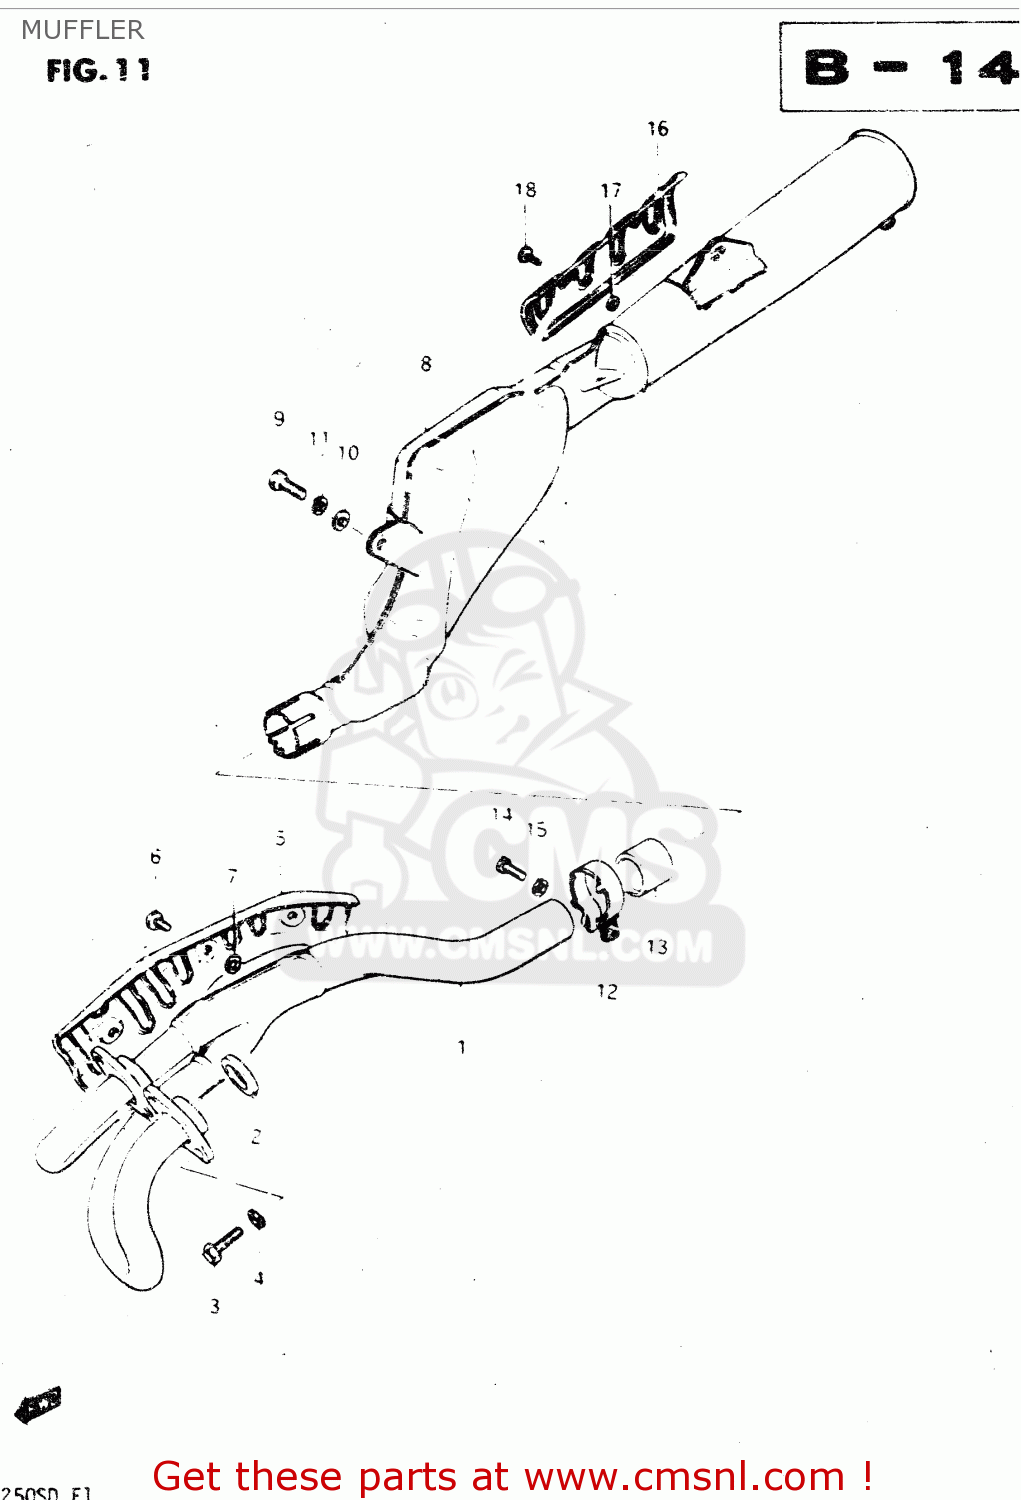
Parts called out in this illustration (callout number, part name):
1	PIPE,EXHAUST
2	GASKET,EXHAUST PIPE (NAS)
3	BOLT
4	LOCK WASHER
5	COVER,EXHAUST PIPE
6	SCREW
7	GASKET 6.2X12X1.5 (MCA)
8	MUFFLER ASSY
9	BOLT
10	WASHER,8.5X16X
11	LOCK WASHER
12	CLAMP
13	CONNECTOR,MUFFLER
14	BOLT 8X35
15	WASHER,8.5X16X
16	COVER,MUFFLER
17	GASKET 6.2X12X1.5 (MCA)
18	SCREW
